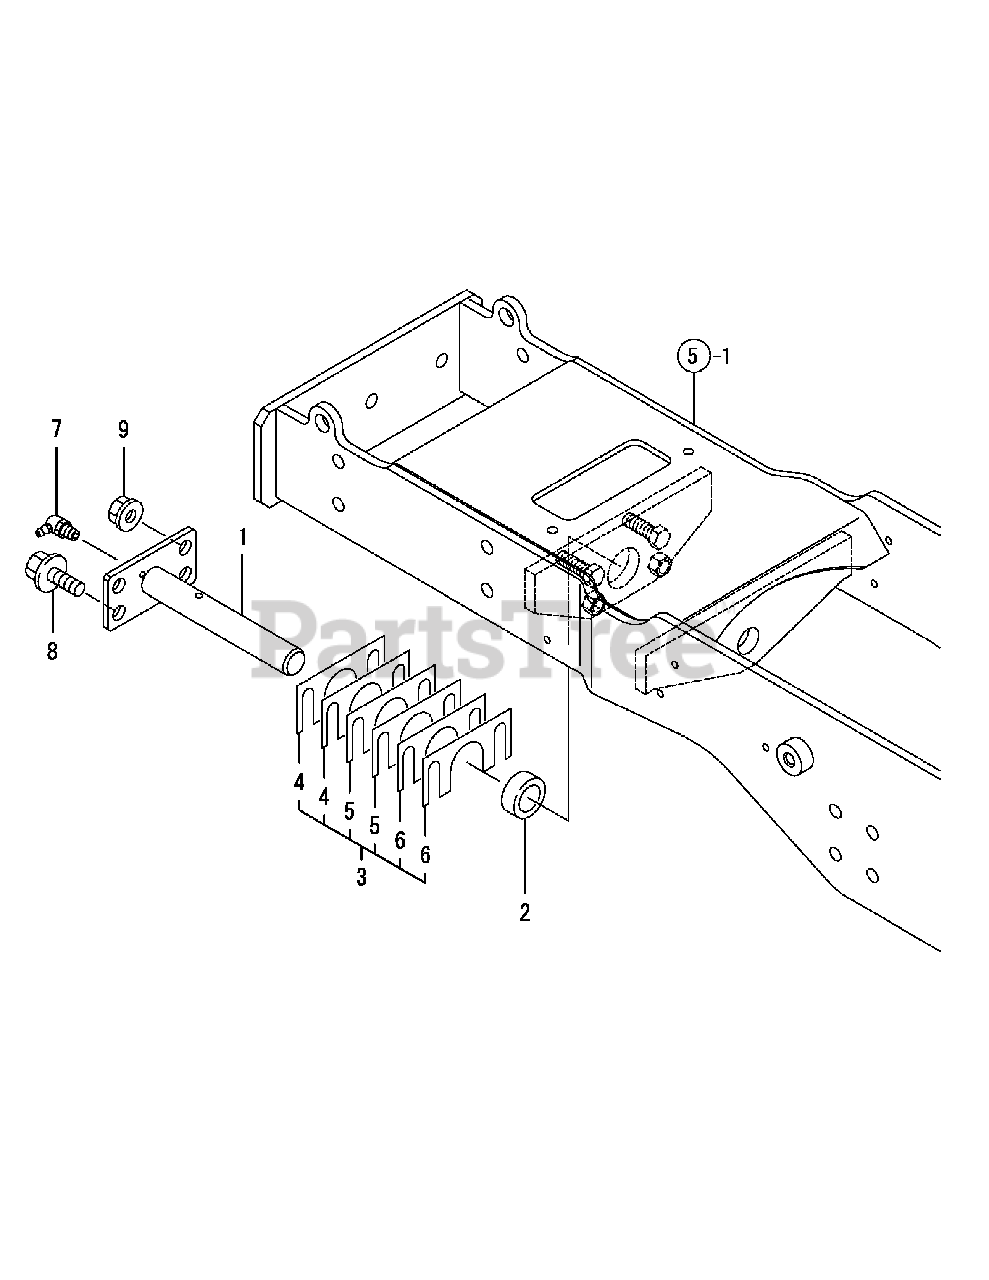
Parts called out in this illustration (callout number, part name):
2	Bush, Center Pin
3	Shim Kit, Center Pin
4	Shim, Center Pin 0.2
5	Shim, Center Pin 0.5
6	Shim, Center Pin 1.0
7	Grease Fitting
8	Bolt M12X 30 Plated
